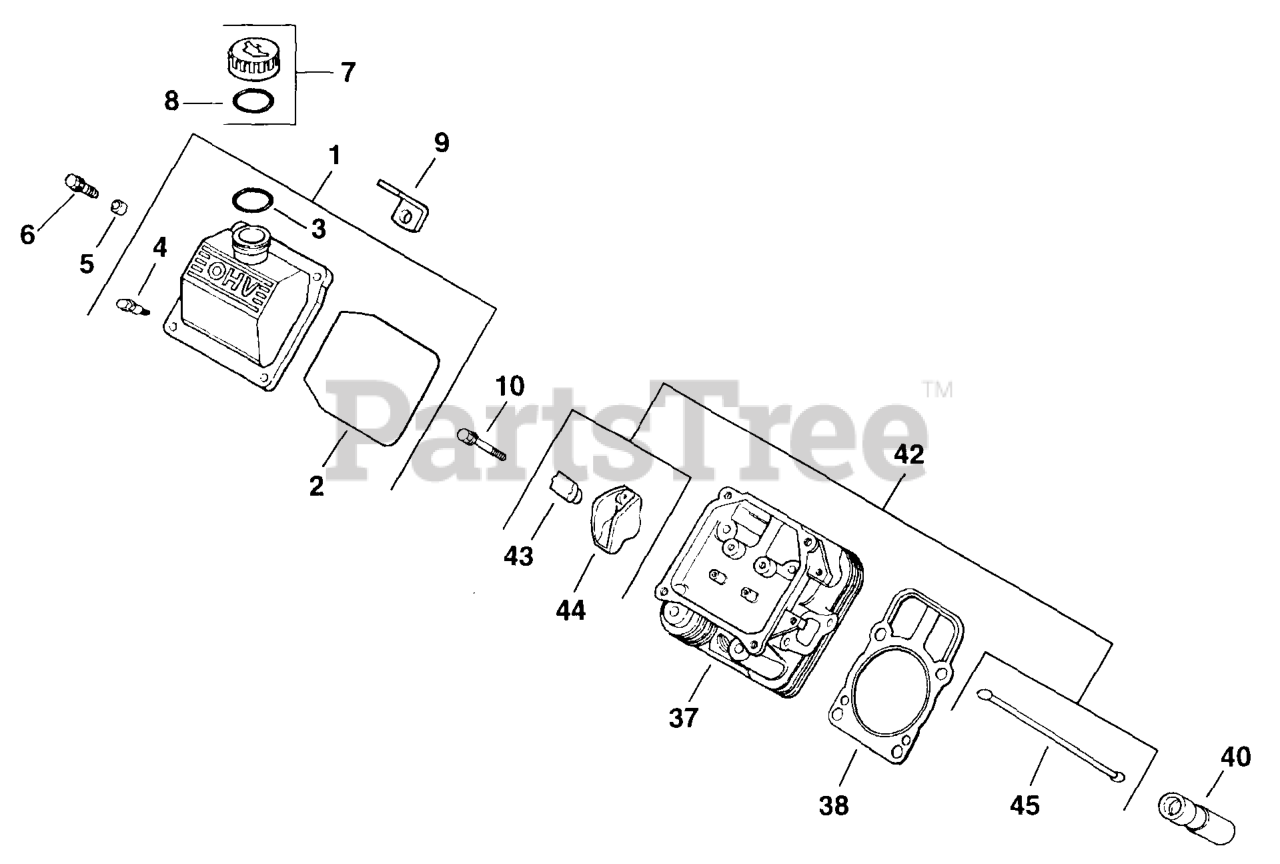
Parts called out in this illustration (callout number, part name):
1	Kit, Valve Cover - Oil Fill
4	Screw, Hex. Cap - Shoulder M6x1.0x23
7	Kit, Oil Fill Cap
9	Strap, Lifting
10	Screw, Hex. Flange M6x1.0x34
37	Head Assembly, #2 Cylinder
38	Gasket, Cylinder Head
40	Lifter, Valve
42	Kit, Valve Train
43	Pivot, Cylindrical Rocker Arm
44	Arm, Rocker
45	Rod, Push
